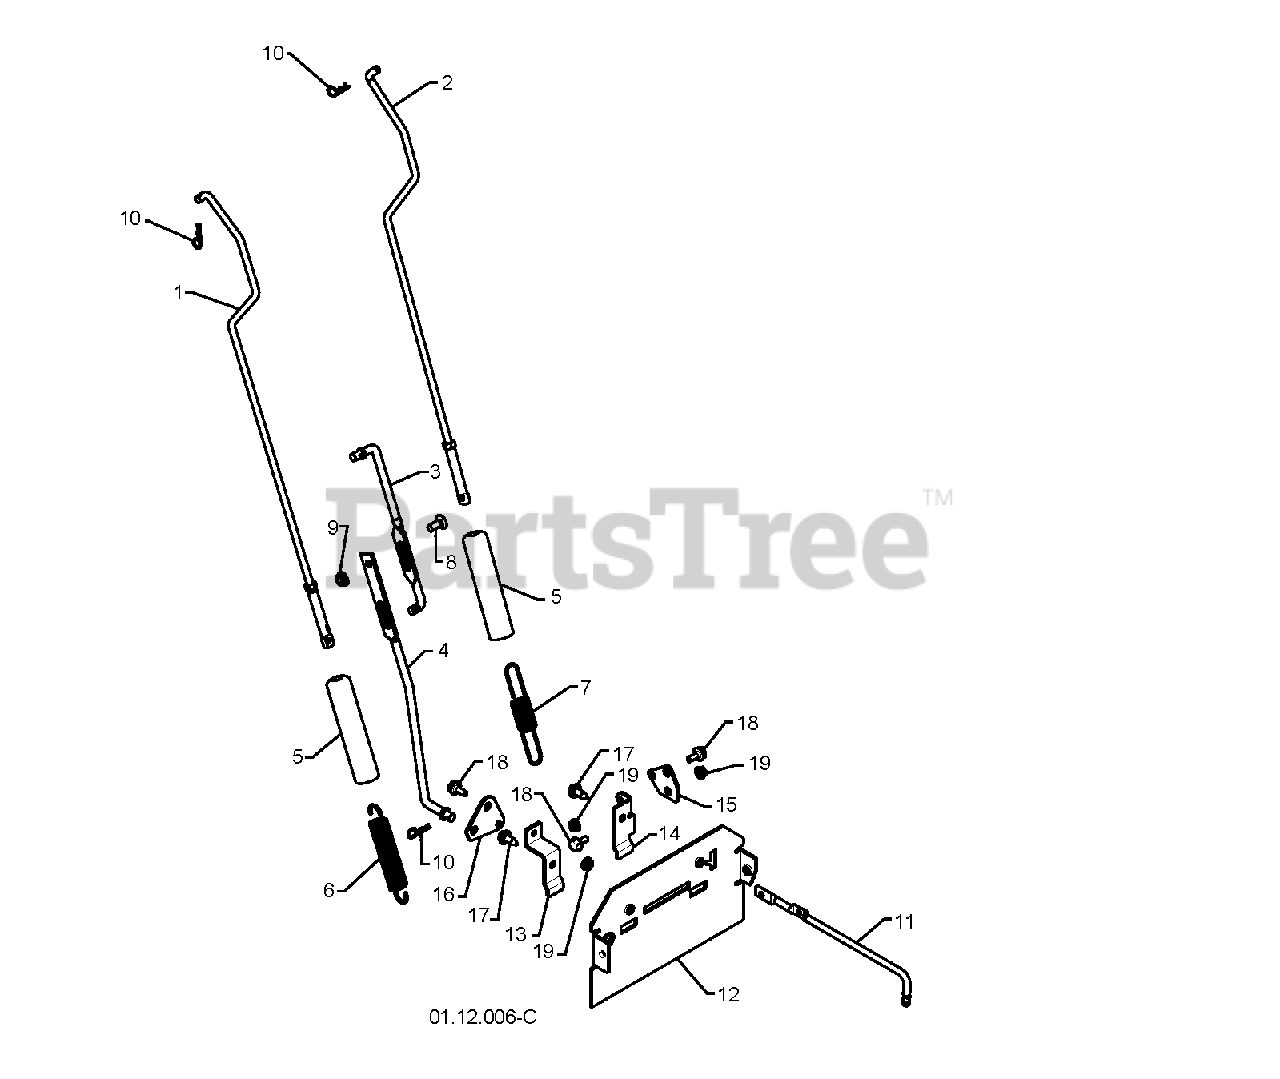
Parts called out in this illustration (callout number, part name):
1	ROD.ASM.IMPELLER
2	ROD.ASM.TRACTION
3	ROD, UPPER SPEED CONTROL
4	ROD, LOWER SPEED CONTROL
5	SLEEVE, SPRING
6	SPRING, AUGER CONTROL
7	SPRING, TRACTION DRIVE
9	NUT.FLANGE.5/16
10	SPRING RETAINER
11	ROD.CLUTCH.YELLOW.ZINC(VT)
13	BRACKET.SHIFTER.PLATE.BZP
14	BRACKET.CLUTCH.PLATE.BZP
15	PLATE.CLUTCH.BZP
16	PLATE.SHIFTER.BZP
17	BOLT.HEX.HD.WASHER.5/16-18X.75
18	BOLT.SHOULDER.3/X.25
19	NUT.HEX.FLANGE.1/4
